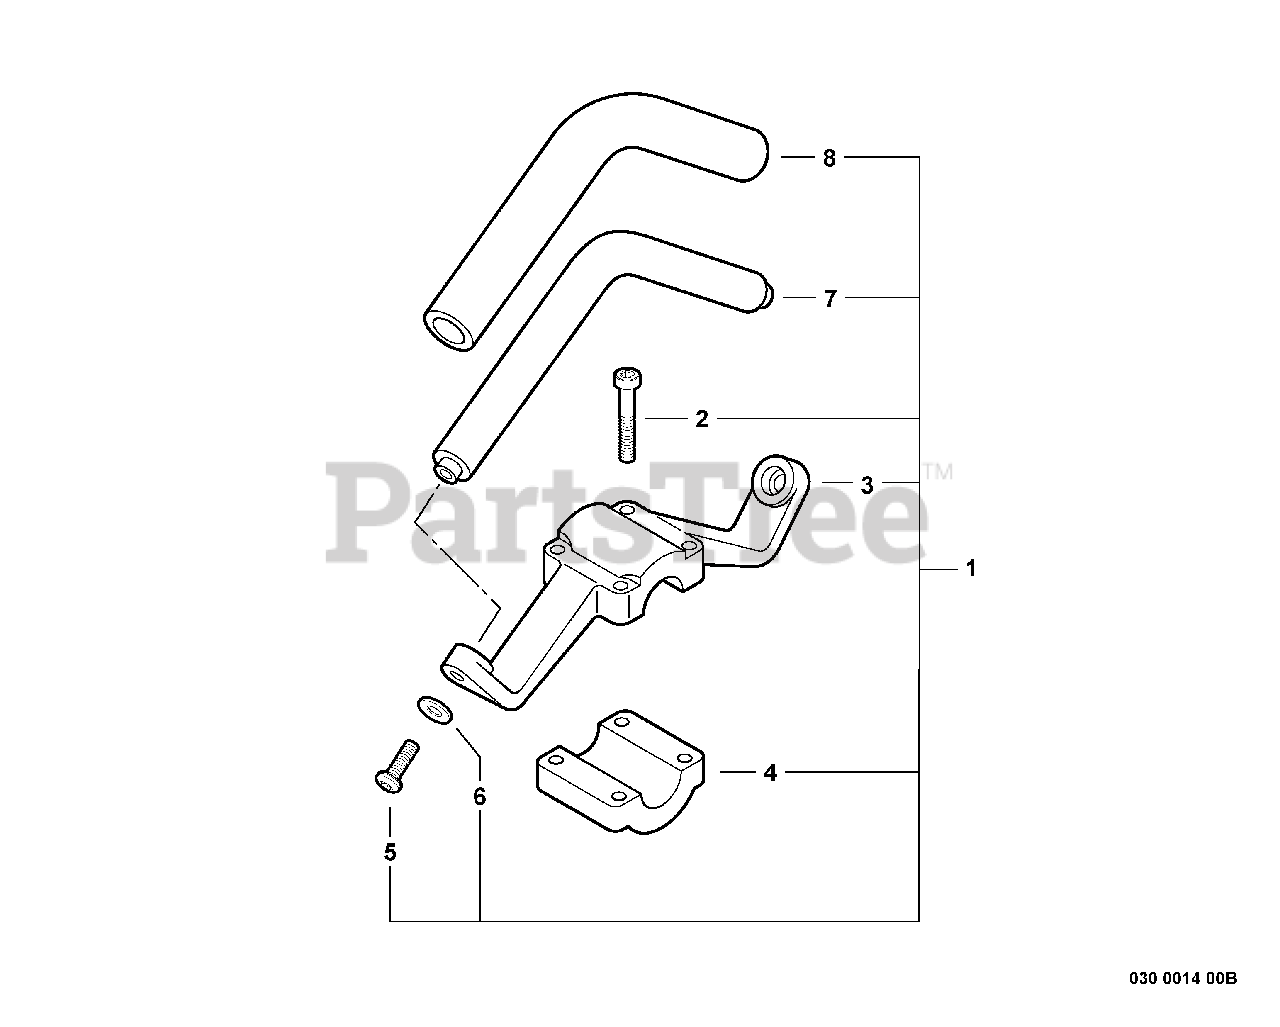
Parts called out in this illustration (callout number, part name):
1	HANDLE ASSY - FRONT
2	SCREW - 5X30
3	BRACKET, HANDLE - UPPER
4	BRACKET, HANDLE - LOWER
5	SCREW - 5X20
6	WASHER - 5
7	HANDLE - FRONT
8	GRIP, HANDLE
